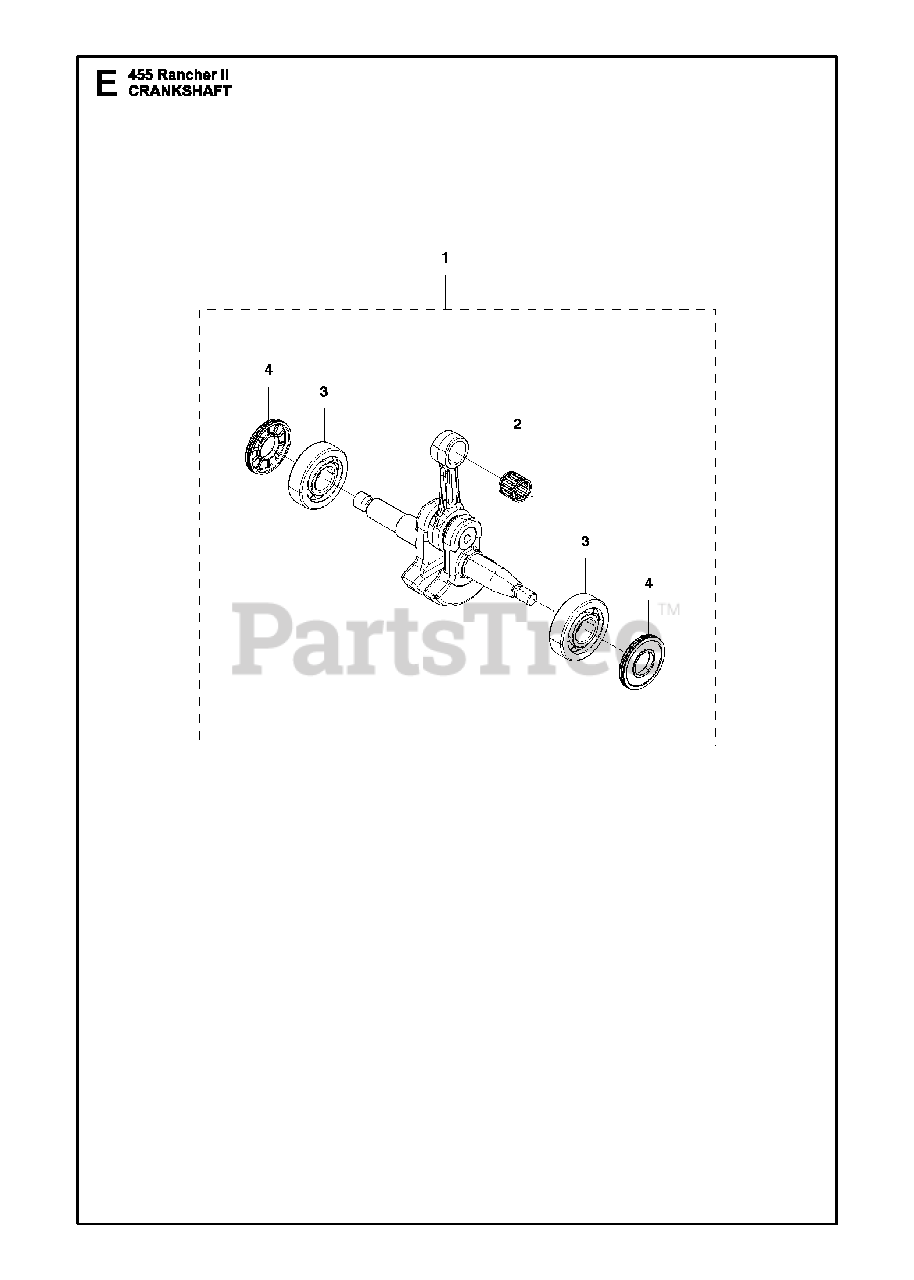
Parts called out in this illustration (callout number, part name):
1	RP CRANKSHAFT CPL
2	NEEDLE BEARING
3	BEARING
4	SEALING
